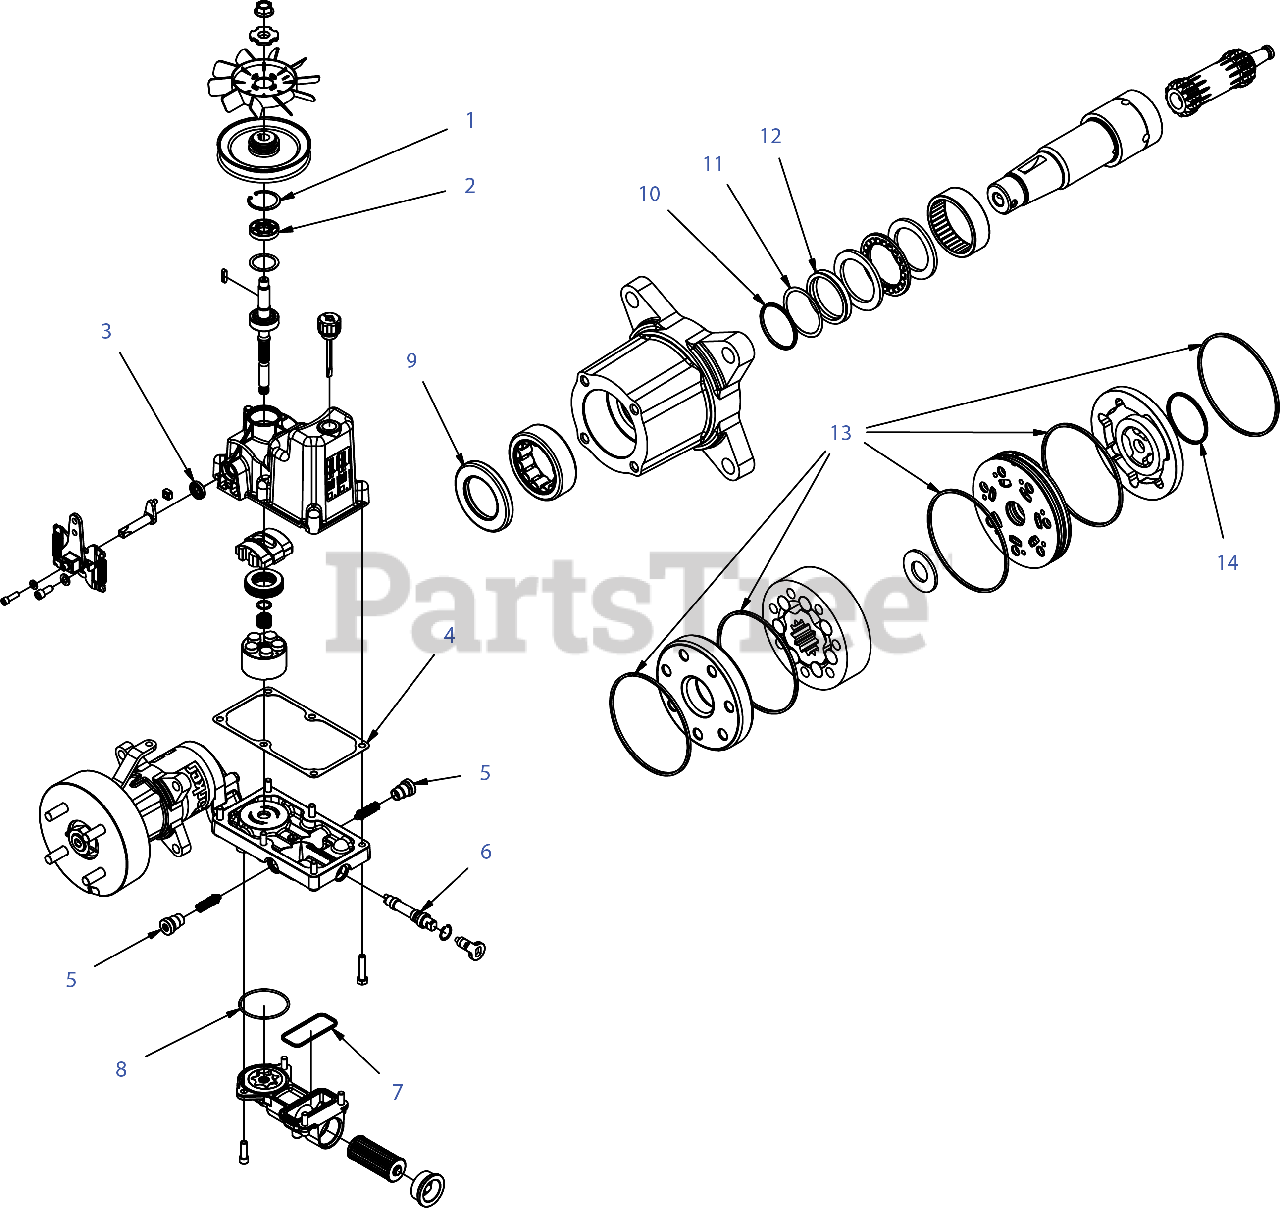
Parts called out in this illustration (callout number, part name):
1	RETAINING RING (INTERNAL)
3	TRUNNION ARM SEAL
5	PLUG AND O-RING ASSEMBLY
6	PACKING, PREFORMED, O-RING SEAL
7	SEAL, CHARGE PUMP COVER
8	PACKING, PREFORMED, O-RING SEAL
9	DIRT AND WATER SEAL
10	BACK-UP RING
11	BACK-UP WASHER
12	SHAFT SEAL
13	SEAL RING - VITON
14	COMMUTATOR SEAL (HI-TEMP)
